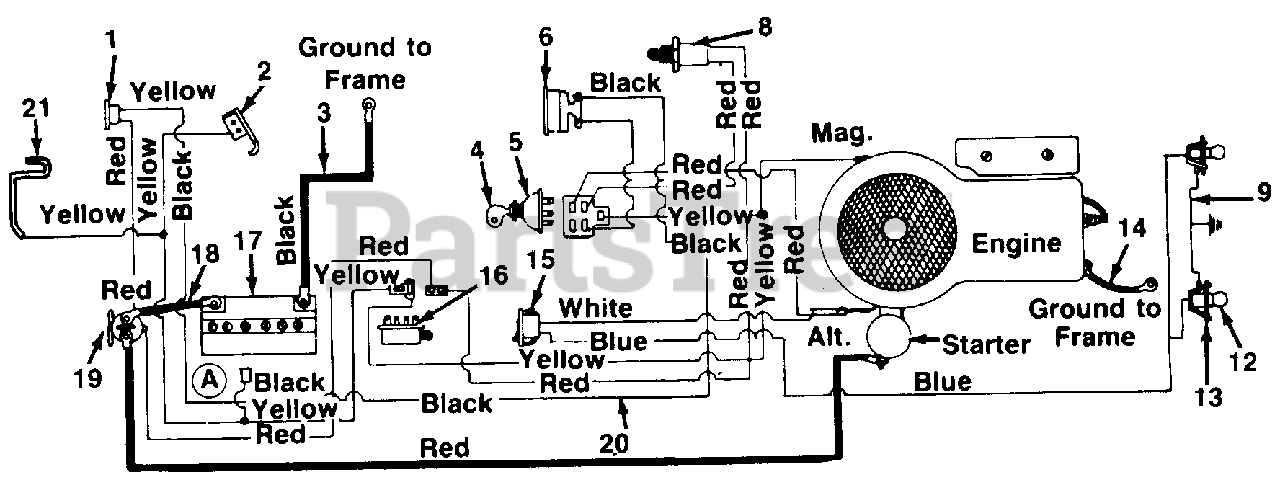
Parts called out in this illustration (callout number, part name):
1	Circuit Breaker
2	Spring-Switch-Reverse
3	Ground Wire 9.0" Lg.
4	Ignition Key
5	Ignition Switch
6	Ammeter
8	Safety Switch
9	Ground Wire
12	Lamp
13	Socket
14	Ground Wire 7.25" Lg.
15	Light Switch
16	Safety Switch
17	Battery
18	Electric Wire w/Boot
19	Solenoid
20	Wire Harness
21	Spring Switch
